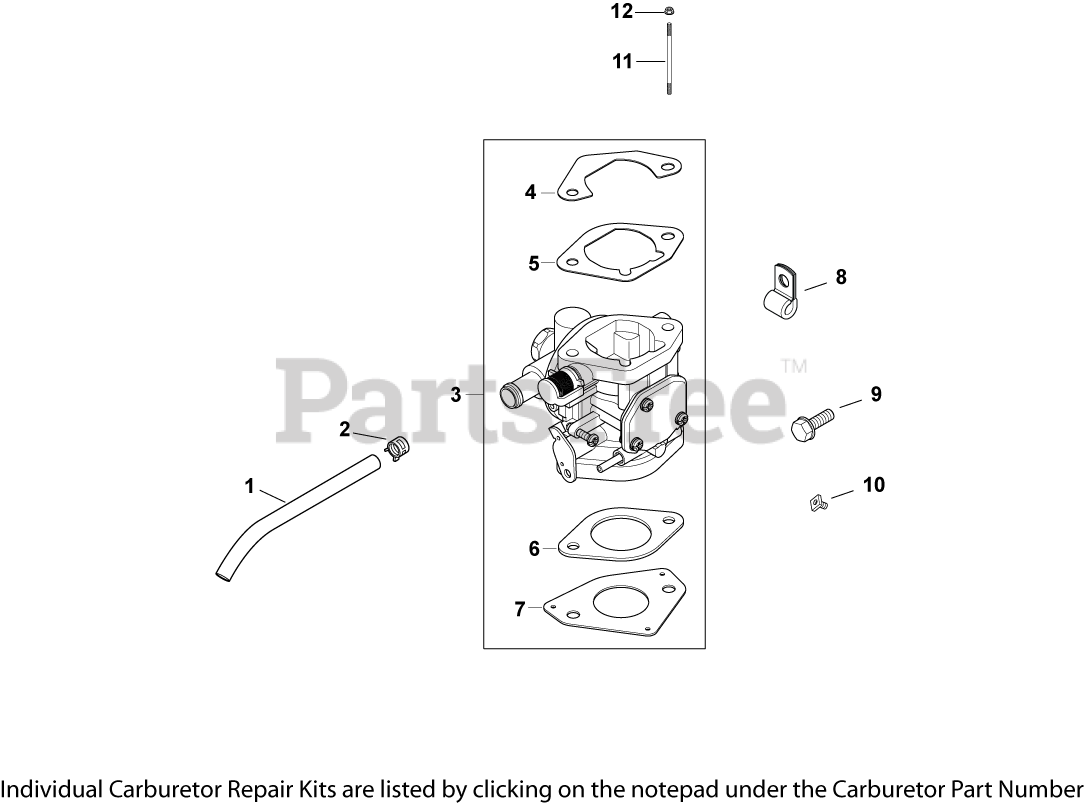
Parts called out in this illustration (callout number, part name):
1	LINE, LP FUEL - DISCONTINUED
2	CLAMP, HOSE-USE 25 237 32-S
3	KIT, CARBURETOR W/GASKETS
4	GASKET, FUEL SPITBACK CUP
5	GASKET, AIR CLEANER BASE
6	GASKET, CARBURETOR
7	GASKET, CARBURETOR
8	CLIP, HOSE
9	SCREW, TAP M6X1.7X18
10	NUT, PLASTIC - BLACK
11	STUD, M6X1.0X106 - (#2507225S)
12	NUT, FLG M6X1.0
